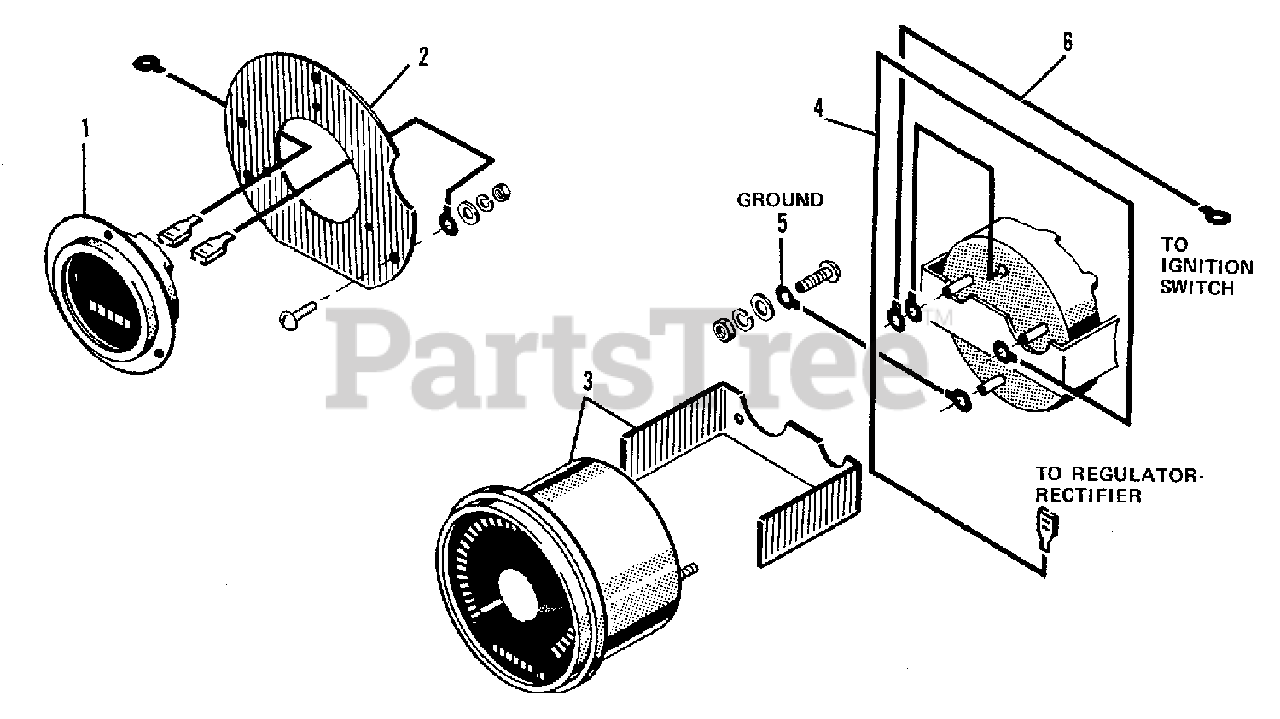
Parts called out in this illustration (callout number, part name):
1	HOURMETER ASSEMBLY
2	NUT, #10NC
2	PLATE, Hourmeter Mounting
2	SCREW, Round Head, #10NC x 3/8
2	LOCKWASHER, #10
2	WASHER, #10, Plain
2	TERMINAL, Wire (Spade - Type)
3	TACHOMETER-Hourmeter Assembly
3	TERMINAL, Wire (Eyelet Type)
3	SCREW, Round Head, #8NC x 1/2
3	NUT, #8NC
3	LOCKWASHER, #8
4	LEAD, Wire (To Regulator - Rectifier)
4	TERMINAL, Wire (Female Slide Type)
5	LEAD, Wire (Ground)
5	WASHER, #10, Plain
6	LEAD, Wire (To Ignition Switch)
